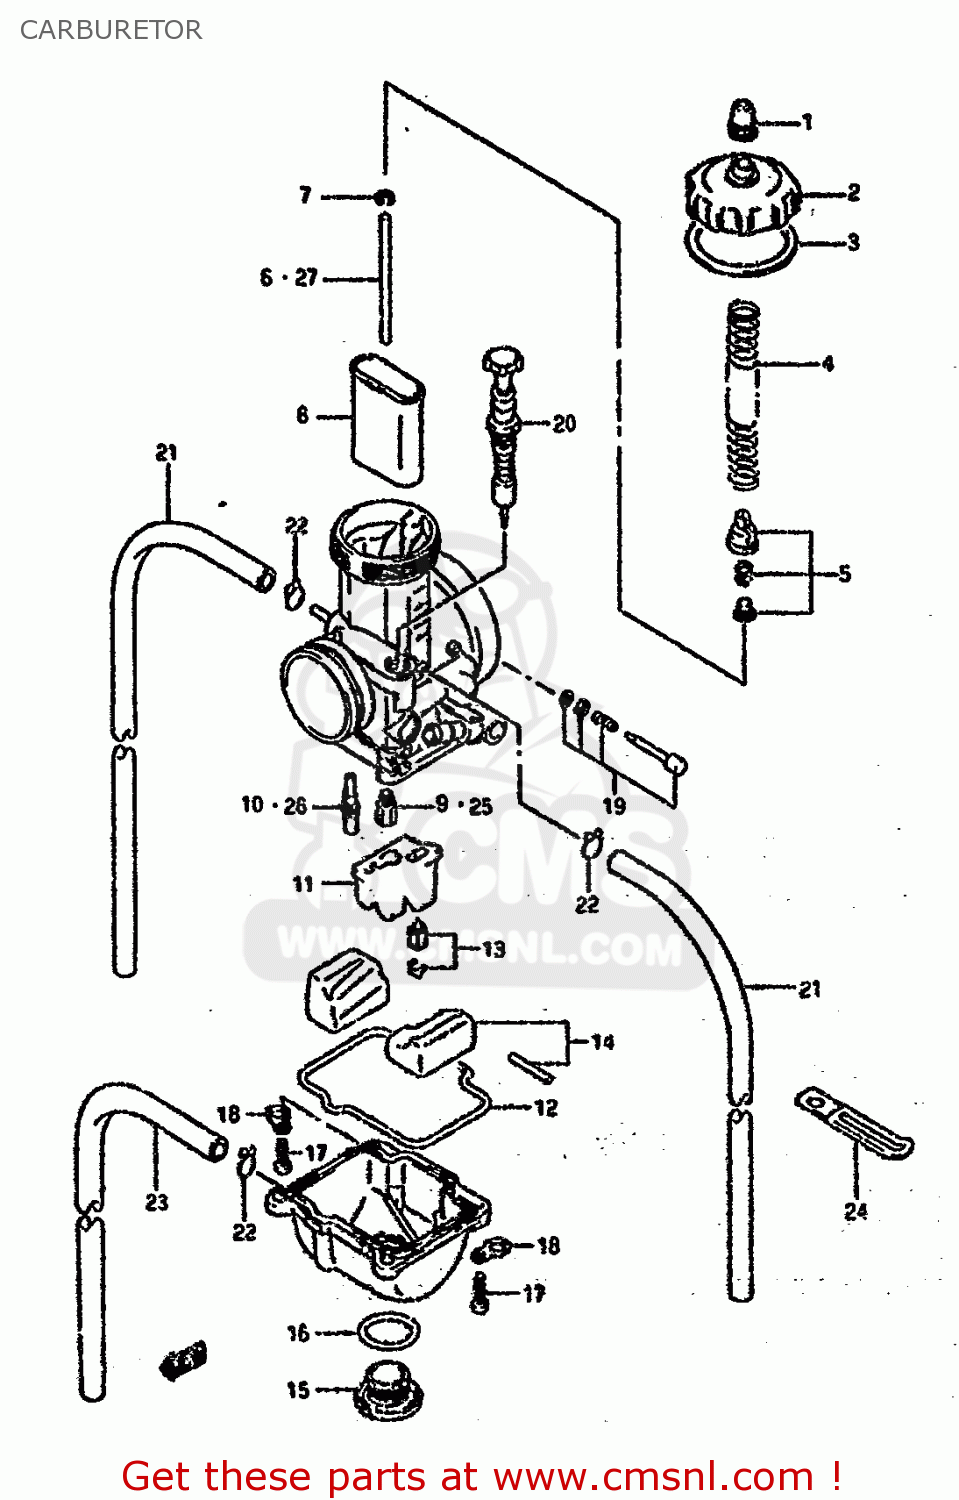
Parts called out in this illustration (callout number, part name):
1	CAP,CARBURETOR
2	CAP,TOP
3	GASKET,TOP CAP
4	SPRING
5	HOLDER SET,CABLE
6	NEEDLE(R1471NS)
7	CLIP,NEEDLE
8	VALVE,PISTON
9	JET,MAIN(200)
10	JET,SLOW(52)
11	HOLDER
12	GASKET,FLOAT CHAMBER
13	VALVE SET,FLOAT
14	FLOAT SET
15	BOLT,DRAIN
16	O RING
17	SCREW
18	PLATE
19	SCREW SET,AIR
20	PLUNGER ASSY
21	HOSE (4X7X440)
22	CLIP
23	HOSE(3.5X6.5X600)
24	CLAMP
25	JET,MAIN(170)
26	JET,SLOW(35)
27	NEEDLE(R1469MS)
